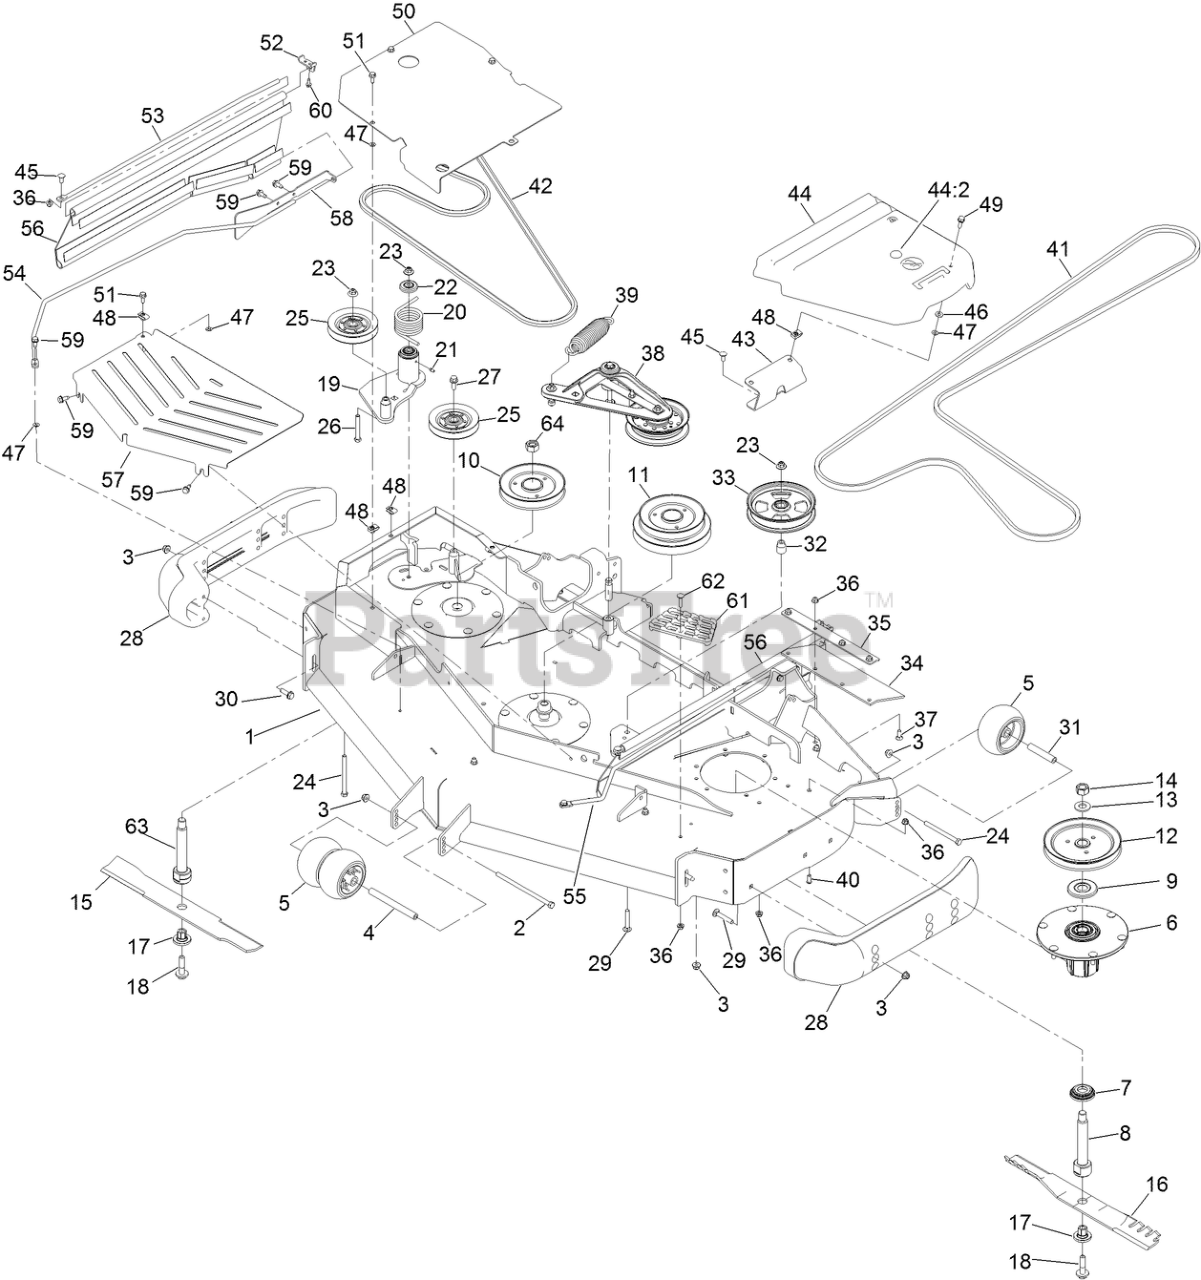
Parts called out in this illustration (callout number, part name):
1	DECK DECAL ASM
2	SCREW-HH
3	NUT-HF, NI
4	SPACER-WHEEL
5	ROLLER-SCALP, ANTI
6	SPINDLE ASM
7	GUARD-BOTTOM
8	SHAFT-SPINDLE
9	GUARD-BEARING, TOP
10	SHEAVE, DOUBLE BLADE DRIVE
11	SHEAVE, DOUBLE BLADE DRIVE
12	SHEAVE-DRIVE, BLADE
13	WASHER
14	NUT-HEX
15	BLADE-20.50 CR LOW FLOW
16	BLADE-20.50 ATOMIC
17	BUSHING-HEX
18	SCREW-SEMS
19	DECK IDLER ASM
20	SPRING-TORSION
21	FITTING-GREASE
22	GUARD-TOP
23	NUT-FLANGE, NI
24	SCREW-HH
25	SHEAVE
26	SCREW-HH
27	SCREW-HHF
28	SKID-BUMPER, DECK
29	SCREW-CARR
30	SCREW-HWHTF
31	TUBE-SPANNER
32	BUSHING-IDLER
33	PULLEY-IDLER, FLAT
34	GUARD-TIRE
35	SUPPORT-OUTER FLAP
36	NUT-HF, NI
37	SCREW-CARR
38	DECK IDLER ASM
39	SPRING-EXTENSION
40	SCREW-HSBH
43	BRACKET-COVER, BELT
44	LH BELT COVER ASM
44:2	PLUG-PLASTIC
45	SCREW-CARR
46	WASHER-THRUST
47	NUT-PUSH
48	NUT-U
49	SCREW-HHF
50	COVER-SPINDLE
51	SCREW-HHF
52	BRACKET-MOUNTING, UPPER
53	ROD-SUPPORT, UPPER
54	ROD SUPPORT WLDMNT, LOWER-RH
55	ROD SUPPORT WLDMNT, LOWER-LH
56	GUARD SIDE
57	SHIELD-FRONT,
58	BRACKET-MOUNTING, REAR
59	SCREW-HWHTF
60	SCREW-HWH
61	STEP-DECK
62	SCREW-CARR
63	SHAFT-SPINDLE, INT. HEX LH THD
64	NUT-HEX,LH,LOCK
